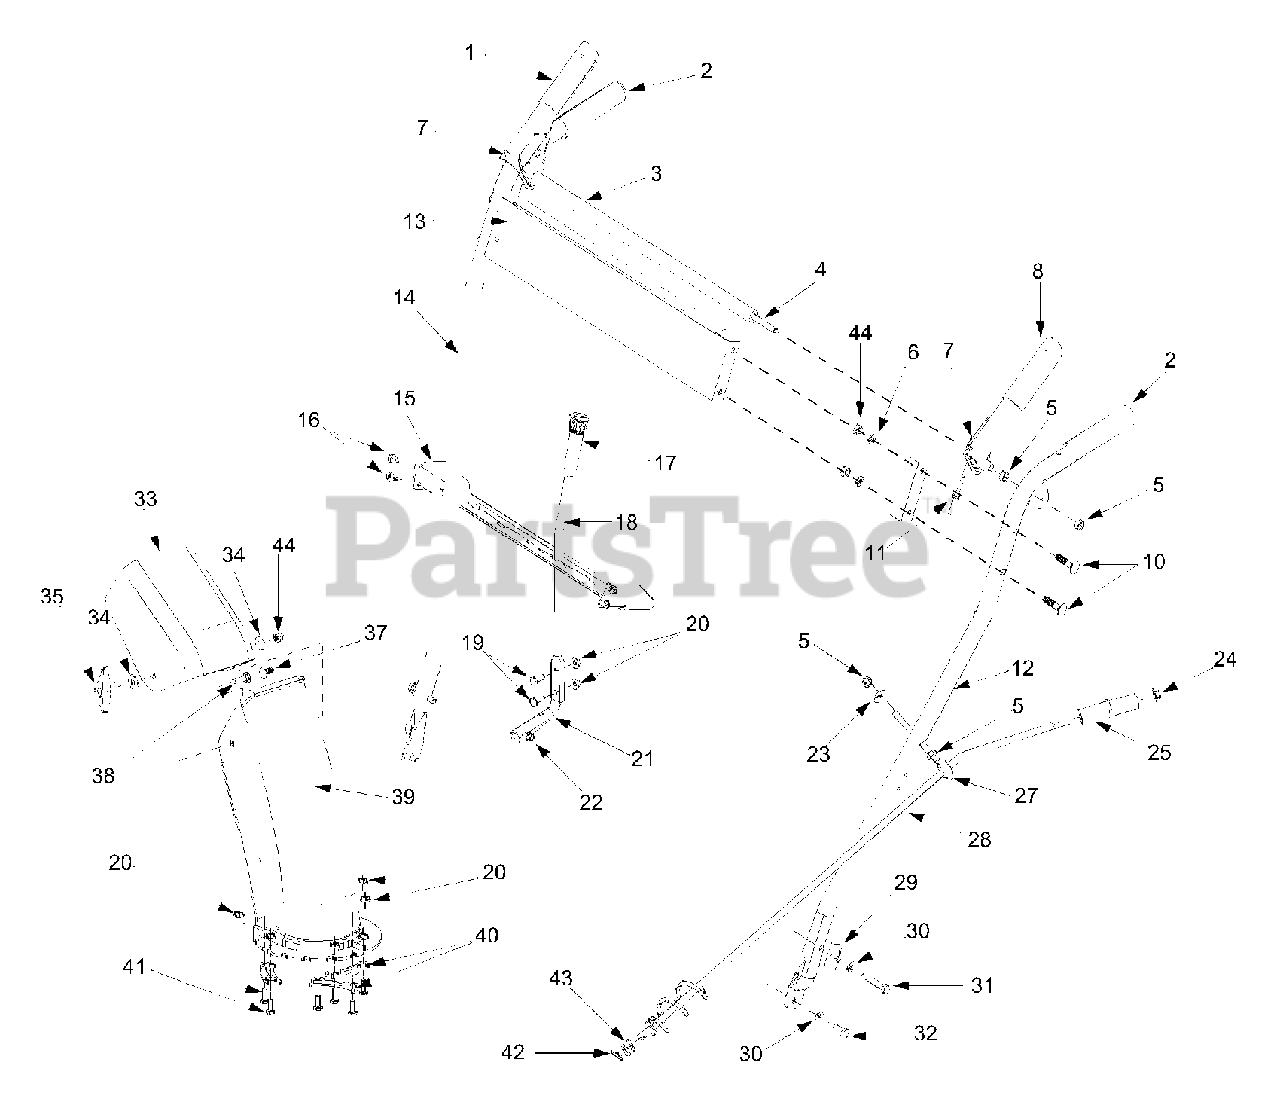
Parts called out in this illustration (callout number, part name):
1	Clutch Lever Assembly - RH
3	Pivot Rod Cover
4	Pivot Rod
5	Hex Nut 5/16-18
6	Lock Washer 5/16
7	Rubber Bumper
8	Clutch Lever Assembly - LH
10	Carriage Bolt 5/16-18 x 1.50
11	"Z" Fittings For Control CablesZ - Cable
16	Hex Washer Screw 1/4-20 x .50
19	Hex Cap Screw 1/4-20 x .75
20	Hex Lock Nut 1/4-20
21	Shift Lever Spring
22	Hex Washer Screw 1/4-20 x 1.0
23	Bell Washer
24	Push Cap
25	Chute Knob
27	Eyebolt
28	Chute Directional Control Assembly
29	Handle Tab
30	Lock Washer 5/16
31	Hex Cap Screw 5/16-18 x 1.75
32	Hex Cap Screw 5/16-18 x .75
33	Upper Chute
34	Washer 5/16
37	Carriage Bolt 5/16-18 x .75
38	Carriage Screw 5/16-18 x 1.0
39	Lower Chute
40	Flange Keeper
41	Hex Cap Screw 1/4-20 x .75
42	Cotter Pin
43	Flat Washer 3/8
44	Hex Patch Nut 5/16-18 Gr. 5
